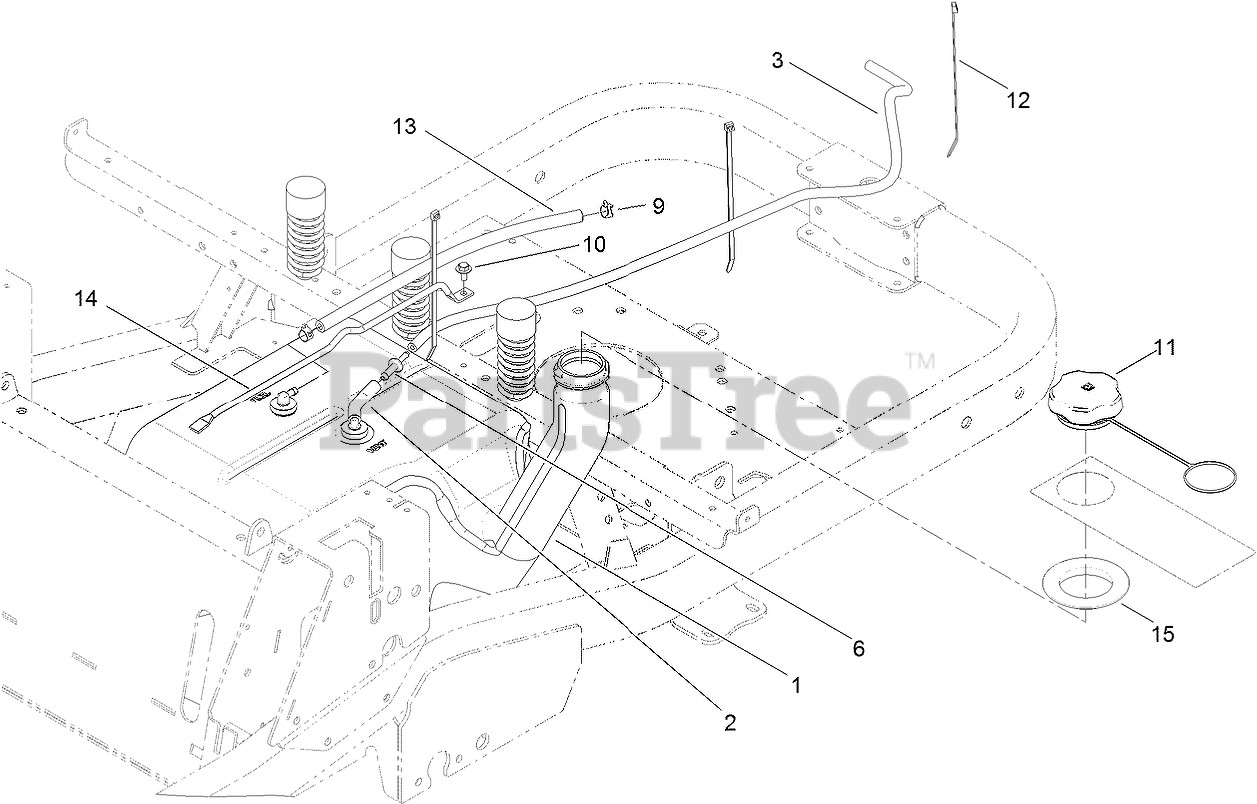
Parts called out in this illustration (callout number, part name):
1	FUEL TANK ASM
2	HOSE-FUEL
3	HOSE-FUEL
6	ADAPTER-ORIFICE
9	CLAMP-HOSE
10	SCREW-HHFTF
11	CAP-FUEL
12	TIE-CABLE
13	HOSE-FUEL
14	ROD-TANK, GAS
15	SEAL-TANK
